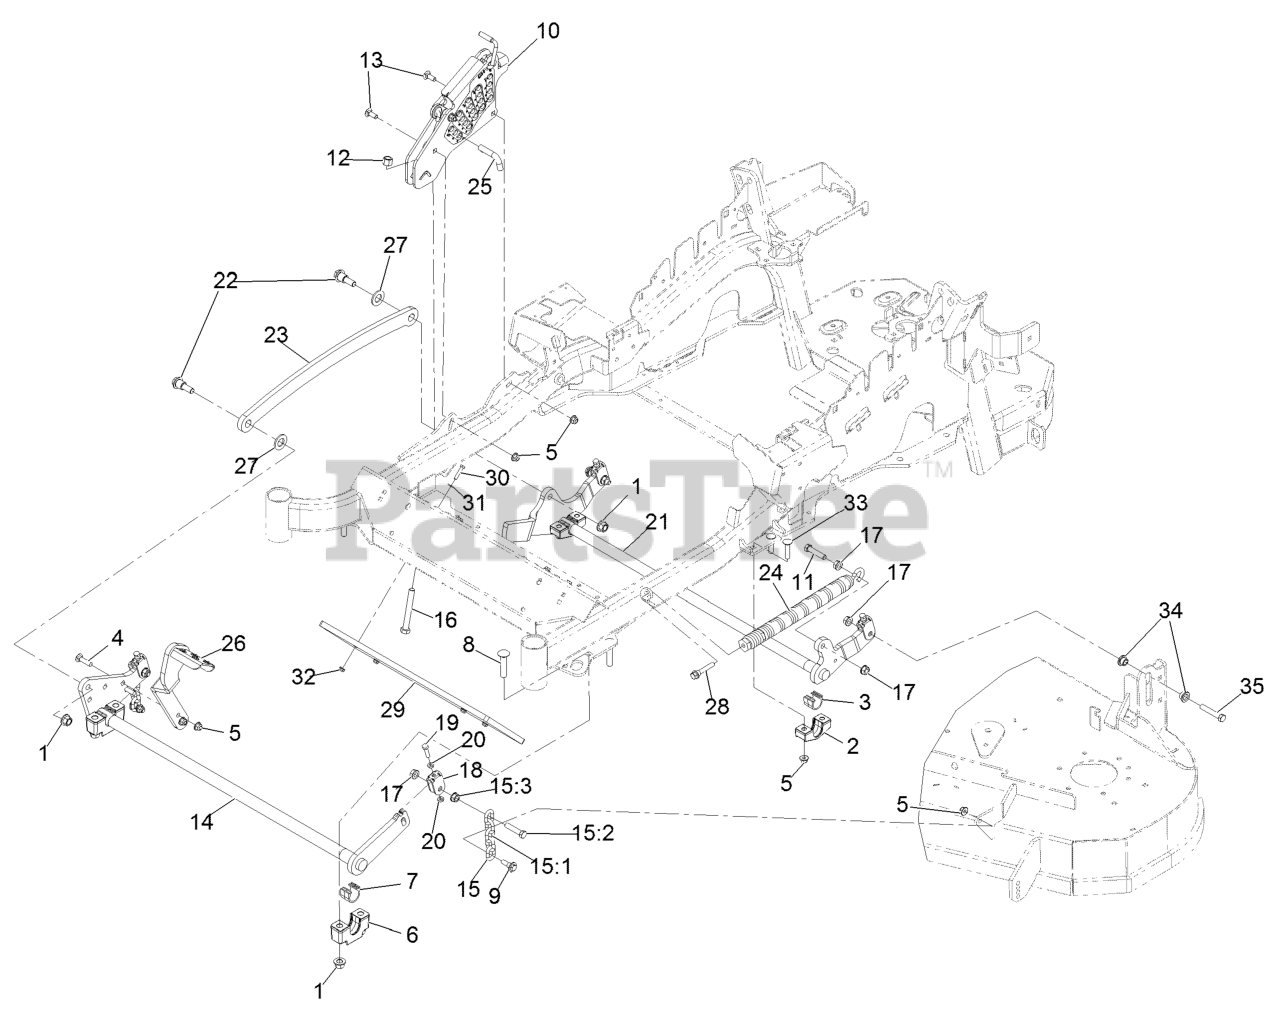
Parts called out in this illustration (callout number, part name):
1	Nut-Lock 1/2-13
3	BEARING-CROSS SHAFT, REAR
4	SCREW-CARR
5	NUT-HF, NI
6	SUPPORT-CROSS SHAFT, BEARING
7	BEARING-CROSS SHAFT, FRON
8	Bolt-Carriage 1/2-13 X 2 1/2 Spl Neck
9	SCREW-SHOULDER, HHF
10	HOC ASM
11	SCREW-HH
12	NUT-LOCK, NI
13	BOLT-CARR
14	DECKLIFT-FRONT
15	DECK LIFT CHAIN ASM
15:1	CHAIN-LIFT, DECK
15:2	SCREW-HH
16	BOLT-TAP
18	YOKE-ADJUST, DECK
19	SCREW-HH
20	NUT-JAM
21	LIFT-DECK, REAR
22	SCREW-SHOULDER, HHF 1/2-13 X 1.12
23	LINK-LIFT, DECK
24	SPRING-EXTENSION
25	PIN-HOC
26	LEVER-FOOT
27	WASHER-FLAT
28	BOLT-SHOULDER
29	WEIGHT,TOE BOARD
30	SCREW-HH
31	WASHER-FLAT
33	SCREW-CARR
34	BUSHING-FLANGED
35	SCREW-HH
